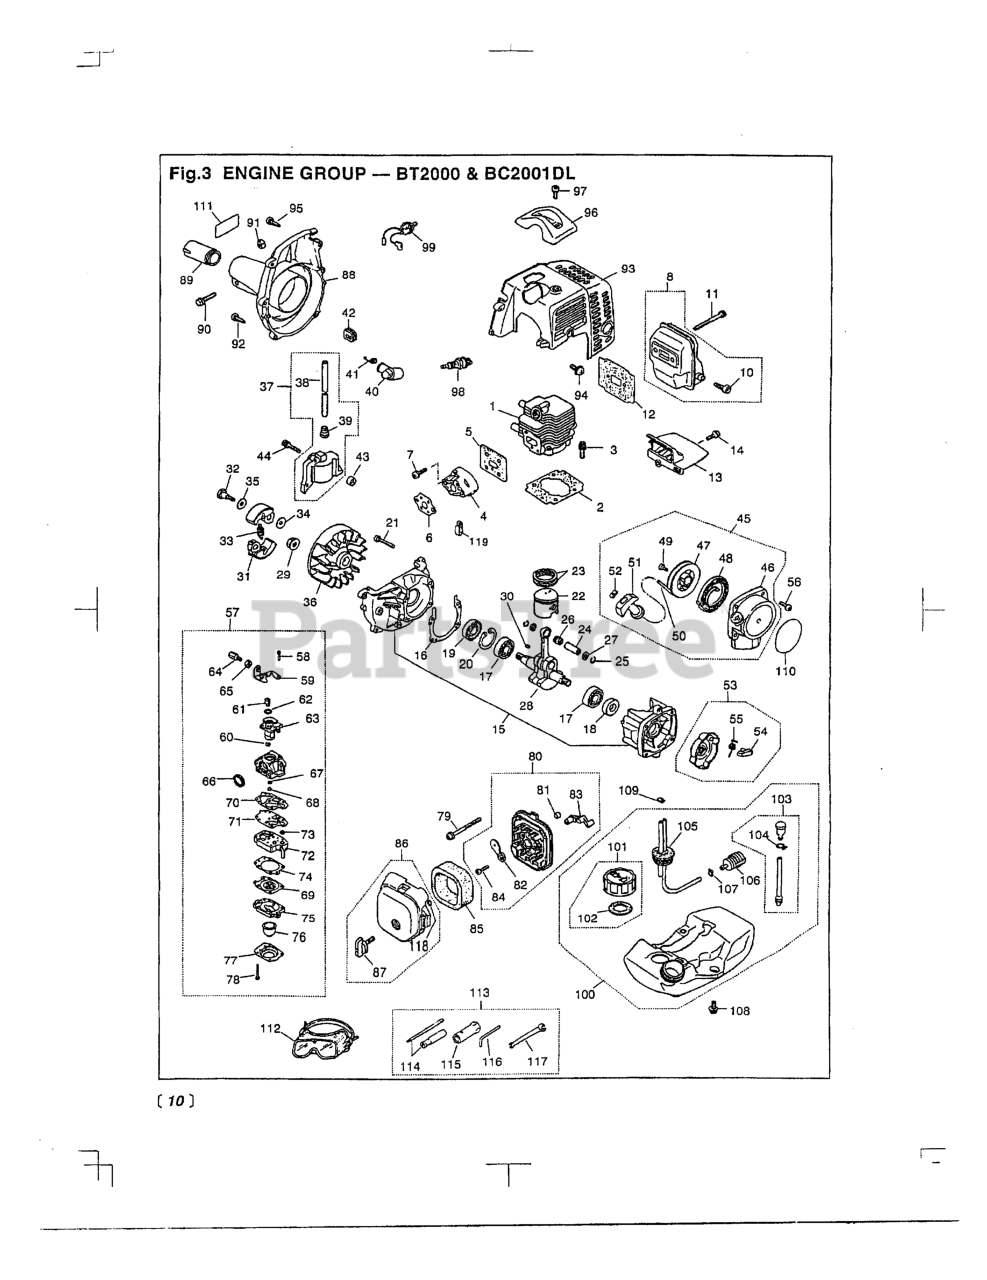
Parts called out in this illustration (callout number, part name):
1	CYLINDER
3	BOLT, M5 X 22
7	SCREW, M5X20 (RPLS.1400-75510)
8	MUFFLER ASSY (RPLS 5501- )
10	ARRESTER (RPLS 5850-15140)
11	BOLT, M5 x 50
12	GASKET, MUFFLER
14	SCREW, M4 X 16
15	CRANKCASE
17	BEARING
18	SEAL, OIL (RPLS 1100-21210)
19	SEAL, OIL (RPLS 1140-21220)
20	RING, SNAP, M28 x 1.2
21	BOLT, M5 X 30
22	PISTON (REPLACES 1140-41110)
23	RING, PISTON (RPLS 1850-41210)
24	PIN, PISTON 5x8x26
25	RING, SNAP (RPLS 1101-41320)
27	WASHER
28	CRANKSHAFT (RPLS 1850-42000)
30	KEY
32	BOLT
33	SPRING, CLUTCH (RPLS-51220)
34	WASHER, FLAT (USE 182303)
36	ROTOR
37	COIL ASSY (RPLS 5500-71200)
38	CORD
39	CAP
41	SPRING
42	GROMMET
43	SPACER (RPLS -71260)
44	BOLT
45	RECOIL ASSEMBLY
46	CASE
47	REEL
48	SPRING, SPIRAL
49	SCREW (RPLS -75150)
51	KNOB
52	PLATE, STOPPER
53	PULLEY ASSY (RPLS -75210)
54	RATCHET (RPLS 1850-75220)
55	SPRING, RETURN
56	SCREW, M4 X 16
57	CARBURETOR (RPLS-81000)
58	SCREW
60	RING
61	SWIVEL
62	WASHER
63	VALVE ASSY
64	SCREW, CABLE ADJUSTER
65	NUT, CABLE ADJUSTER
66	RING, PACKING
67	RING, O
68	JET
69	DIAPHRAGM (USE 4810-81260)
70	GASKET, PUMP
71	DIAPHRAGM
72	BODY, PUMP
74	GASKET, DIAPHRAGM
75	BODY, PURGE
76	PUMP, PRIMING
77	COVER, PUMP
78	SCREW
79	SCREW, M5 x 60
80	BODY-A (RPLS -82101)
81	SLEEVE
82	PLATE, CHOKE (RPLS-82130)
83	LEVER, CHOKE
84	SCREW (REPLACES 50030272)
85	ELEMENT
87	KNOB (RPLS -82220)
88	HOUSING COMPLETE
90	BOLT, M6x35 (RPLS -50635)
91	NUT, M6 X 5
92	SCREW, M5X20 (RPLS.1400-75510)
94	SCREW, M5 x 12
95	SCREW, HOUSING
96	GUARD, PLUG
97	SCREW,M5 X 14 (RPLS 1400-15510
99	SWITCH
101	CAP (RPLS -85200)
102	PACKING
104	CLIP
105	PIPE COMPLETE
106	FILTER (RPLS 1850-85300)
107	CLIP (REPLACES 2841-31280)
108	SCREW
109	CLIP
113	TOOL SET
114	SCREWDRIVER
115	SOCKET, HEX, 3/4
116	BAR
117	SPANNER, 8 X 10 (RPLS 2540- )
118	RING
119	CLAMP
